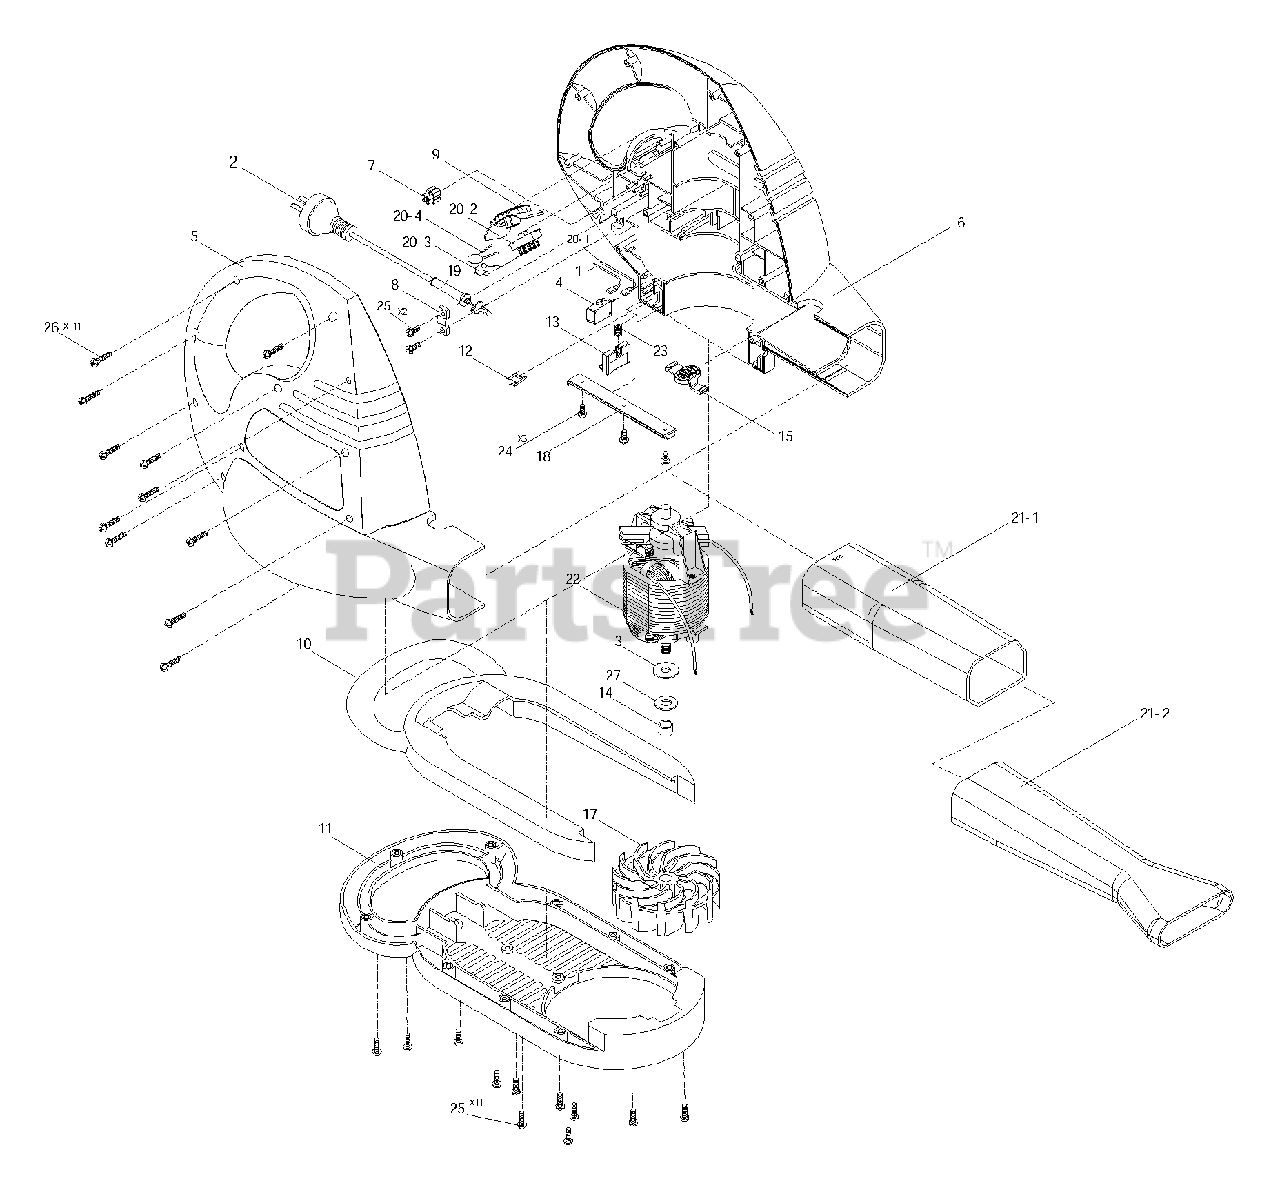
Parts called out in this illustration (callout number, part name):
2	POWER CORD
5	HOUSING (L)
6	HOUSING (R)
7	TERMINAL BLOCK
8	STRAIN RELIEF
10	UPPER HANDLE
11	LOW HANDLE
12	SPRING PLATE
13	SAFETY SHAFT
14	SHAFT SLEEVE
18	TRANSMISSION SHAFT
19	CORD GUARD
20	SWITCH ASS'Y
21	ABSORTING TUBE ASS'Y
22	MOTOR 120V
